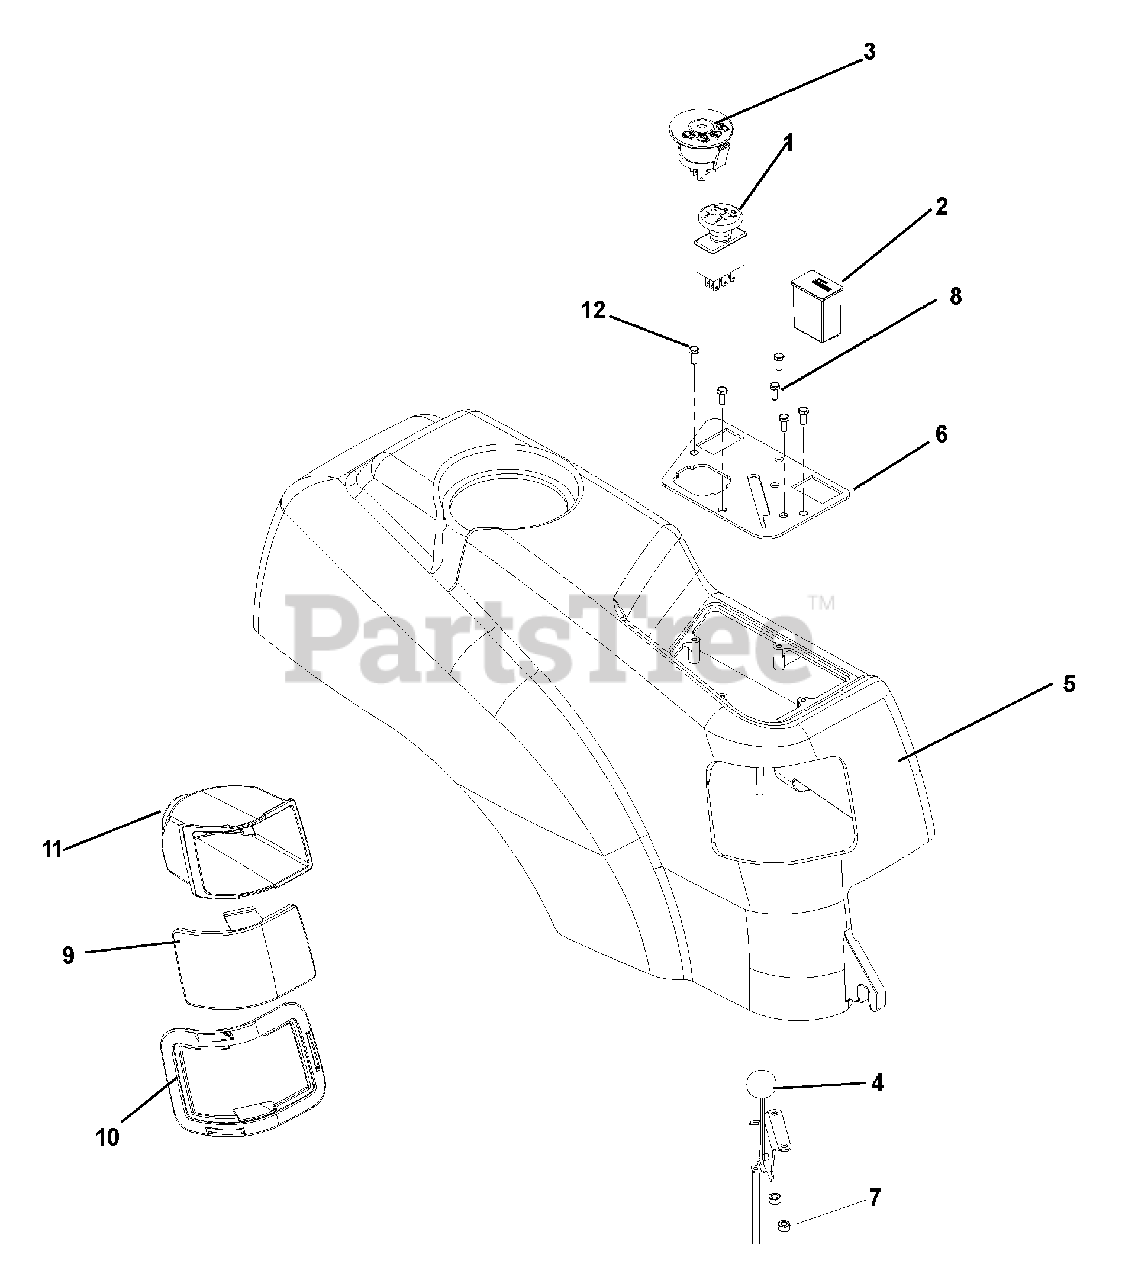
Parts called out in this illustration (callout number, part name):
1	SWITCH
2	HOURMETER
3	IGNITION SWITCH
4	THROTTLE CABLE
5	FENDER, CONSOLE
6	CONSOLE PLATE
7	NUT, #10-24, HEX NYLON RING
8	SCREW #10-24 X 1/2
9	LENS, COLORED, LEFT
9	LENS, COLORED, RIGHT
9	HEADLIGHT LENS, LEFT
9	HEADLIGHT LENS, RIGHT
10	RIM, HEADLIGHT, RIGHT
10	RIM, HEADLIGHT, LEFT
11	HEADLIGHT REFLECTOR, LEFT
11	HEADLIGHT REFLECTOR, RIGHT
12	SCREW #10 - 12 X 3/4
